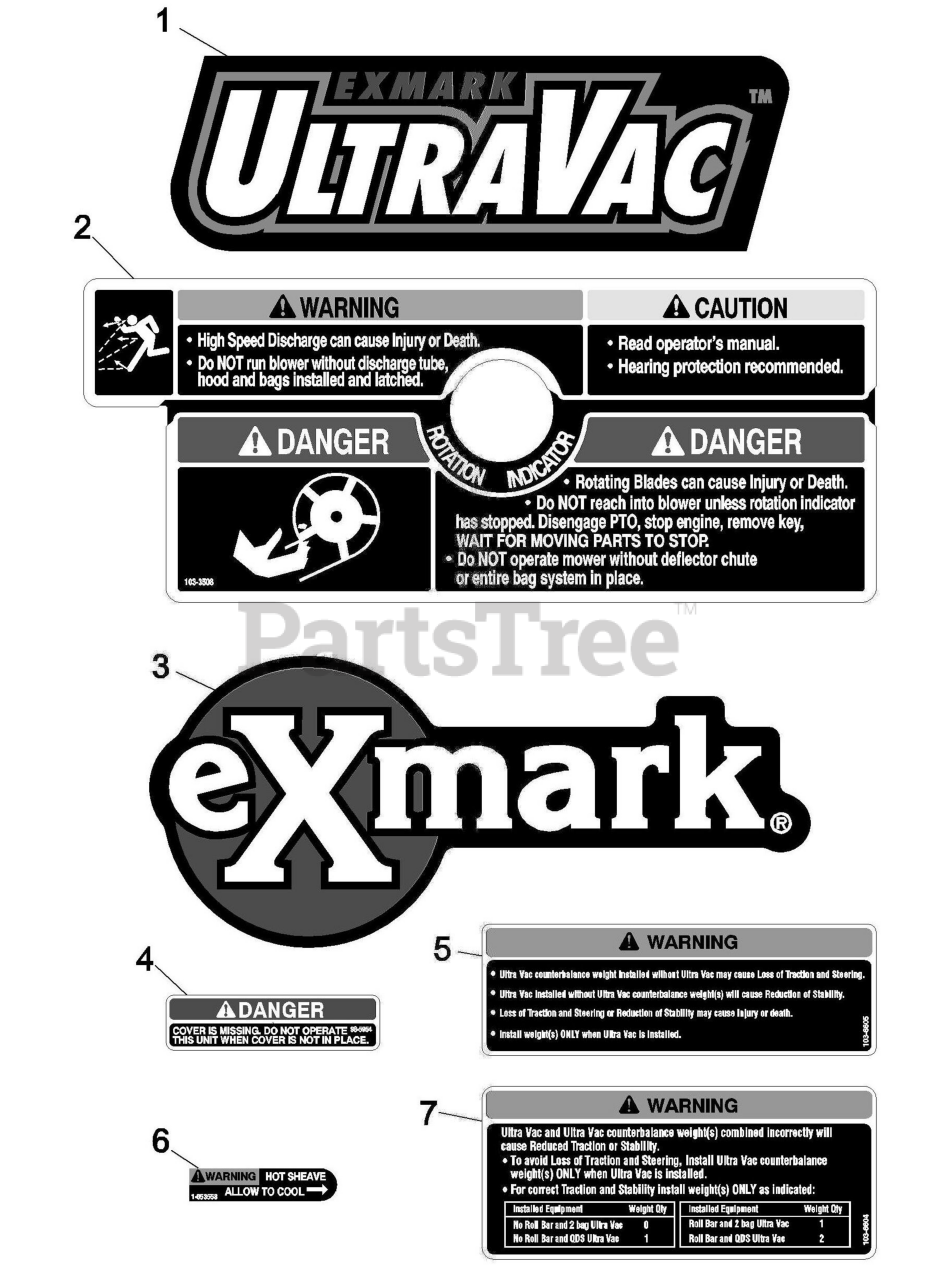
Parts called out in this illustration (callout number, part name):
1	DECAL, ULTRAVAC
2	DECAL-WARNING
3	DECAL, EXMARK LOGO
4	DECAL-COVER, MISSING
5	DECAL,WEIGHT
6	DECAL-WARNING
7	DECAL,WEIGHT
